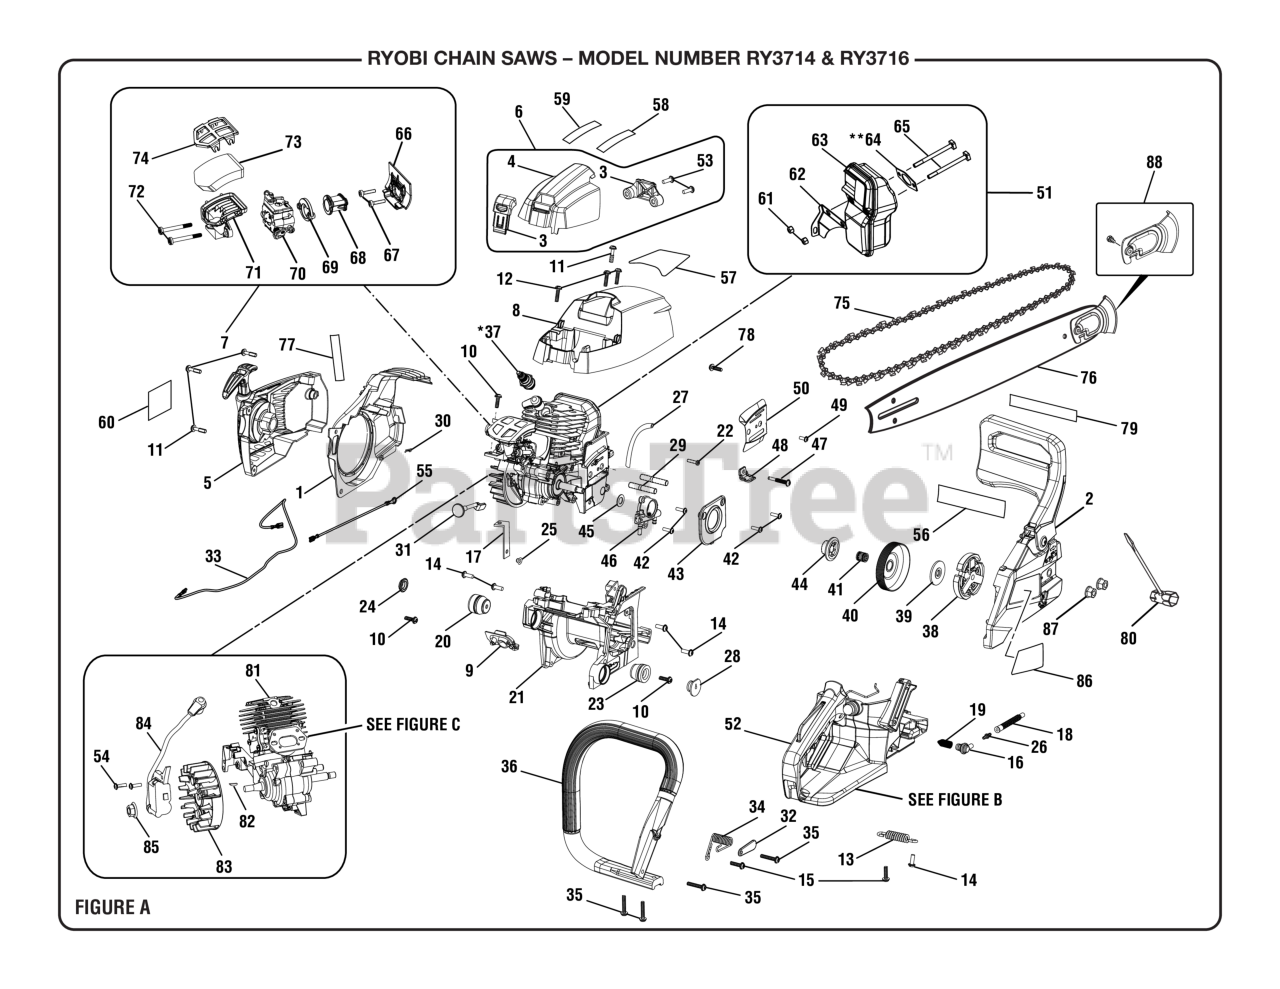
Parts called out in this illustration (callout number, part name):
1	Cylinder Baffle
2	Clutch Cover Assembly
3	Carburetor Cover Latch and Bracket Assembly
4	Carburetor Cover Housing
5	Starter Housing Assembly
6	Carburetor Cover Assembly
7	Intake Assembly
8	Cylinder Housing Assembly
9	Throttle Rod Grommet
10	Screw (M5 x 16 mm, T25 Torx Pan Hd.)
11	Screw, Truss Hd., Plastite (10-14 x 7/8")
12	Screw (M5 x 14 mm, T25 Torx Pan Hd.)
13	Damper Spring
14	Screw (M5 x 0.8 mm, T25 Torx Pan Hd.)
15	Screw (M5 x 14 mm, T25 Torx Pan Hd.)
16	Oil Filter Grommet
17	Band Stopper
18	Rubber, Pipe In Oil Pump
19	Cone Spring
20	Rubber Damper
21	Engine Case
22	Pin (Oil Pump Outlet)
23	Damper Rubber
24	Damper Cap.
25	Starter Case
26	Joint For Pipe In Comp
27	Oil Pump Rubber Tube (Outlet)
28	Damper Cap (T)
29	Bar Stud (5/16-18 x 23.5 mm / 5/16-18 x 18 mm)
30	Spring Clip (Choke Rod)
31	Choke Rod
32	Damper Plate
33	Lead Wire Assembly (Red)
34	Damper Spring
35	Screw (M5 x 27 mm, T25 Torx Pan Hd.)
36	Front Handle
37	Spark Plug (Champion RCJ6Y)
38	Clutch Assembly
39	Thrust Plate
40	Clutch Drum
41	Clutch Drum Needle Bearing
42	Screw (M4 x 14 mm, T20 Torx Pan Hd.)
43	Oil Pump Cover
44	Oil Pump Drive Gear
45	Washer (Oil Pump Drive Gear)
47	Screw (M4 x 33 mm, T25 Torx Pan Hd.)
48	Chain Catcher.
49	Screw (M4 x 12 mm, T20 Torx Pan Hd.)
50	Chain Guard Plate.
51	Exhaust Assembly.
52	Chassis & Handle Components
53	Screw (M4 x 10 mm, T20 Torx Pan Hd.)
54	Screw (M4 x 14 mm, T20 Torx Pan Hd.)
55	Lead Wire Assembly (Black)
56	Chain Brake Label (RY3714)
57	Warning Label
58	Starting Label (Right)
59	Starting Label (Left)
60	Starting House Label (RY3818)
61	Hex Nut (M5, Muffler)
62	Muffler Bracket
64	Gasket (Muffler)
65	Bolt (Muffler, M5 x 62 mm)
67	Bolt (M9 x 19 mm, T25 Torx Pan Hd.)
68	Intake Boot
69	Intake Bracket
70	Carburetor Assembly
71	Air Box Base
72	Screw (M5 x 44 mm,T25 Torx Hd. Carburetor)
73	Foam Air Filter
74	Air Filter Retainer
75	14 in. Chain (RY3714, 52 Drive Link)
76	14 in. Guide Bar Assembly (RY3714)
77	Warning Label (Combustion)
78	Screw (M5 x 0.8 mm, T25 Torx Pan Hd.)
79	Pull To Release Brake Label
80	Combination Wrench
81	Short Block
82	WOODRUFF KEY (10 mm X 3 mm)
83	Flywheel Assembly
84	Ignition Assembly
85	Flange Nut (M8, Flywheel)
86	Bar Cover Label
87	Hex Nut (5/16-18 Flange)
88	Bar Nose Kit
